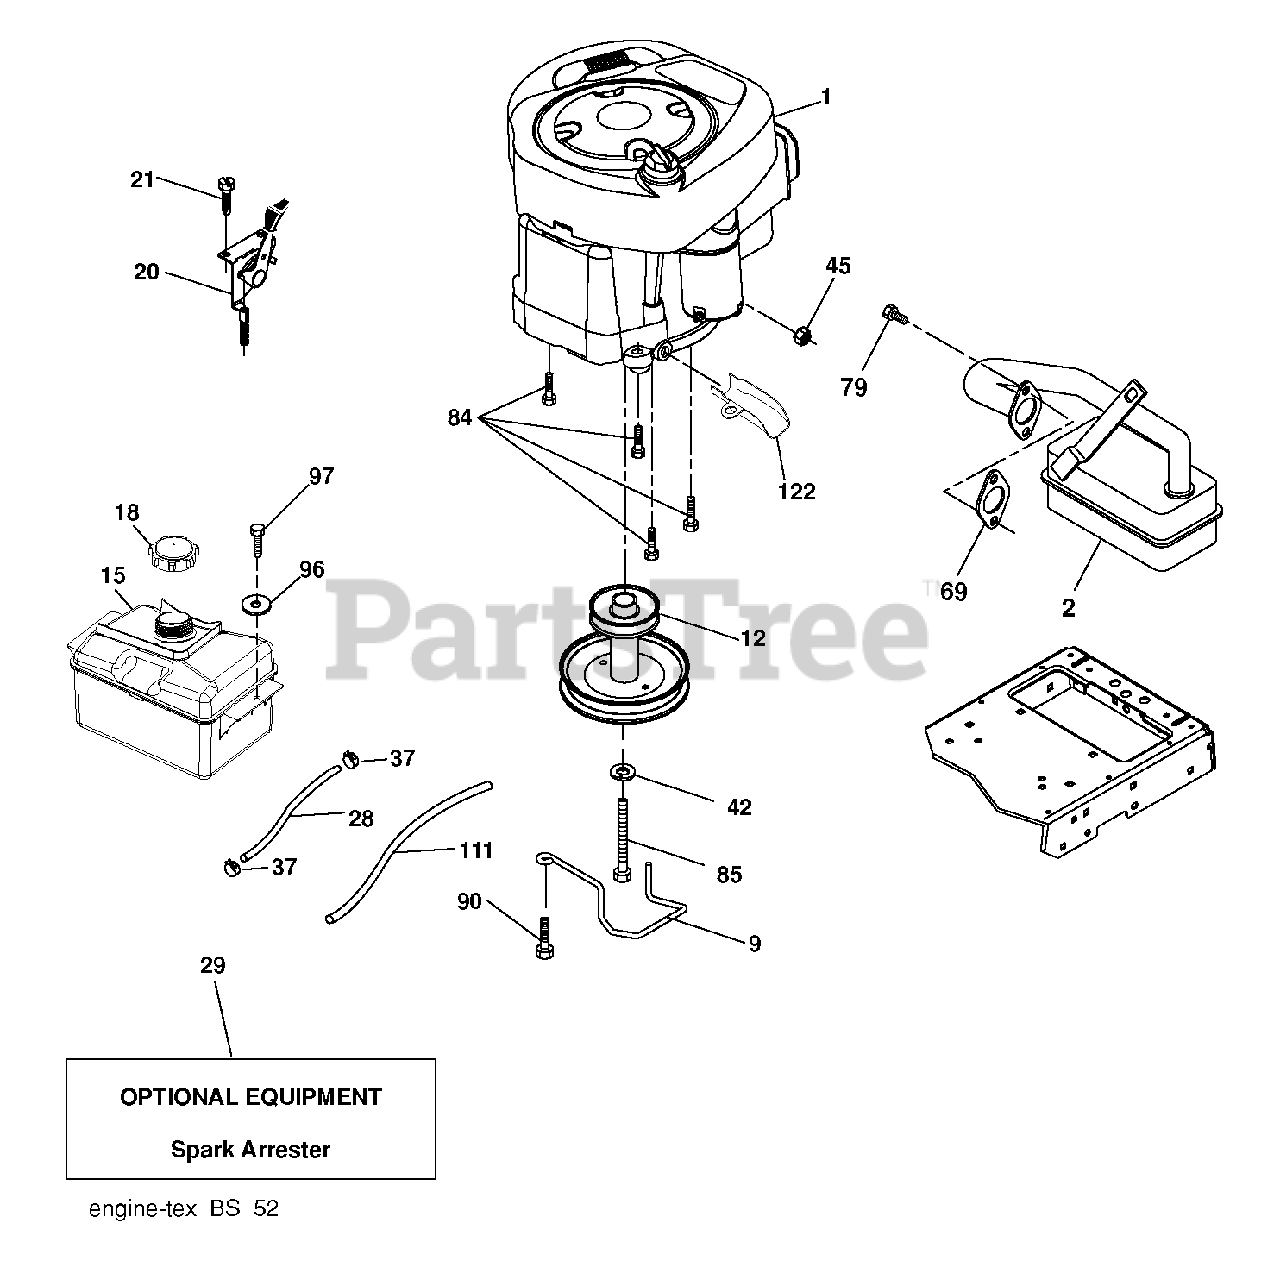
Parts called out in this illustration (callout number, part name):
2	MUFFLER.LT.BRIGGS.14HP.IC/OHV
9	KEEPER BELT ENGINE
12	Engine Pulley
15	TANK.ASM.1.5GAL.FRT.W/CAP.EPA
18	CAP.FUEL.2 WAY VENT
28	LINE.FUEL.20"FRONT.EMI
29	KIT.SPARK ARRESTOR(392390 B&S)
37	HOSE CLAMP
42	LOCKWASHER
45	NUT
79	SCREW.SOCKET HD.5/16-1
84	SCREW.3/8-16
85	BOLT HEX 7/16-20X4-1/4"
90	SCREW 3/8-16X1
96	WASHER
97	SCREW HEXWSHR 1/4-20X3/4
111	RP PURGE LINE
122	EXTENSION DRAIN OIL
